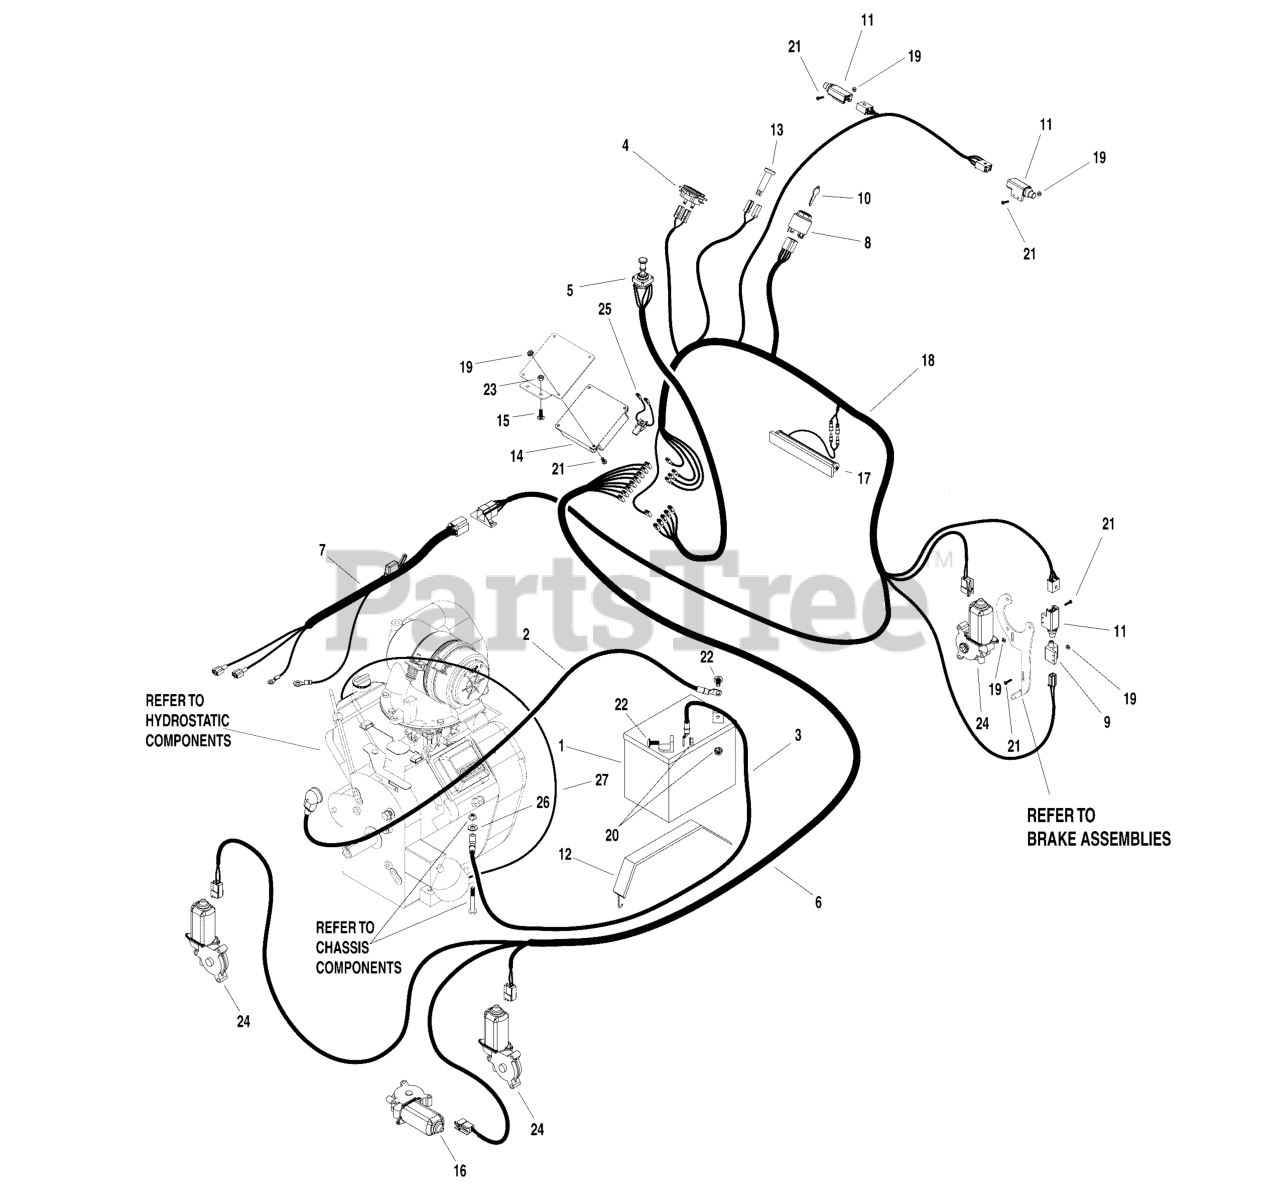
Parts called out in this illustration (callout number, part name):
1	BATTERY
2	BOLT, 1/4-20 X 3/4, FLANGE, CZ
3	NUT, 5/16-18 HEX SERRATED FLANGE (SMALL)
4	METER, TACH/HOUR (104-17-5205)
4-1	WIRE HARNESS, TACH X3,Z3
5	KIT, JOYSTICK UPDATE
6	WIRE HARNESS, DEFLECTOR, X3 JOYSTICK
7	WIRE HARNESS,VANGUARD 23HP
8	SWITCH, IGNITION, SNAP-IN
9	SWITCH, SAFETY (X3-4090)
10	KEY, IGNITION SWITH, 2X (104-17-5608)
11	SWITCH, SAFETY(2P)
12	STRAP, BATTERY
13	LIGHT, WARNING
14	MODULE, CONTROL, CIR BRD (ZP2817)
15	BOLT, 1/4-20 X 3/4, CARRIAGE, CZ (17109)
16	MOTOR, DEFELCTOR, LEFT
17	HEADLIGHT
18	WIRE HARNESS, MAIN, X3 JOYSTICK
19	NUT, #10-32, KEPS, CZ (15106)
20	NUT, 5/16-18 HEX SERRATED FLANGE (SMALL)
21	SCREW, #10-32 X 3/4, ALLEN, SS
22	BOLT, 5/16-18 X 3/4, FLANGE, CZ
23	NUT, 1/4-20 HEX SERR. FLANGE
24	DEFLECTOR, Motor
25	CIRCUIT BREAKER, 15A A-RESET
26	WASHER, 5/16 FLAT, CZ
27	WIRE, OIL SENDING (XP17483)
